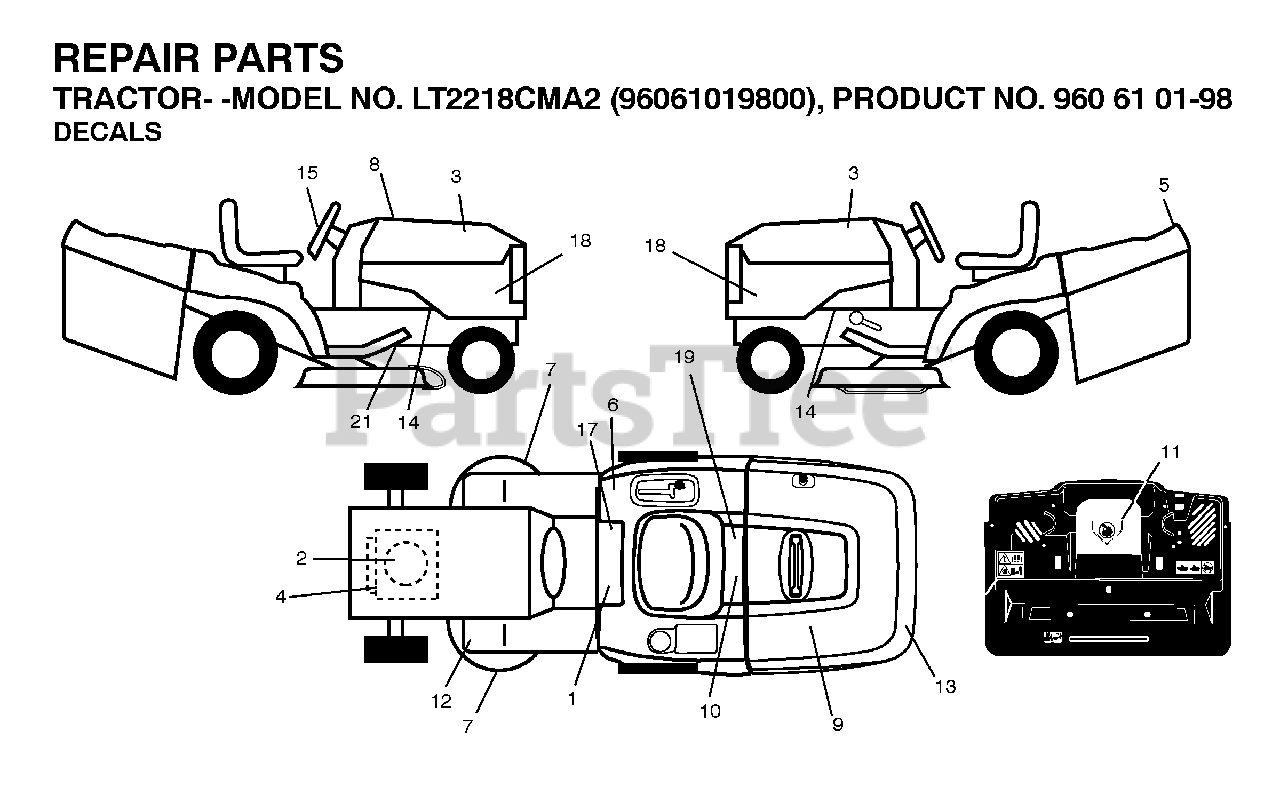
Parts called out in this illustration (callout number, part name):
10	DECAL BTRY SYMBOLS
11	DECAL.INTERNATIONL.CUTFINGER
17	DECAL PARK BRAKE
19	DECAL PARK BRAKE
